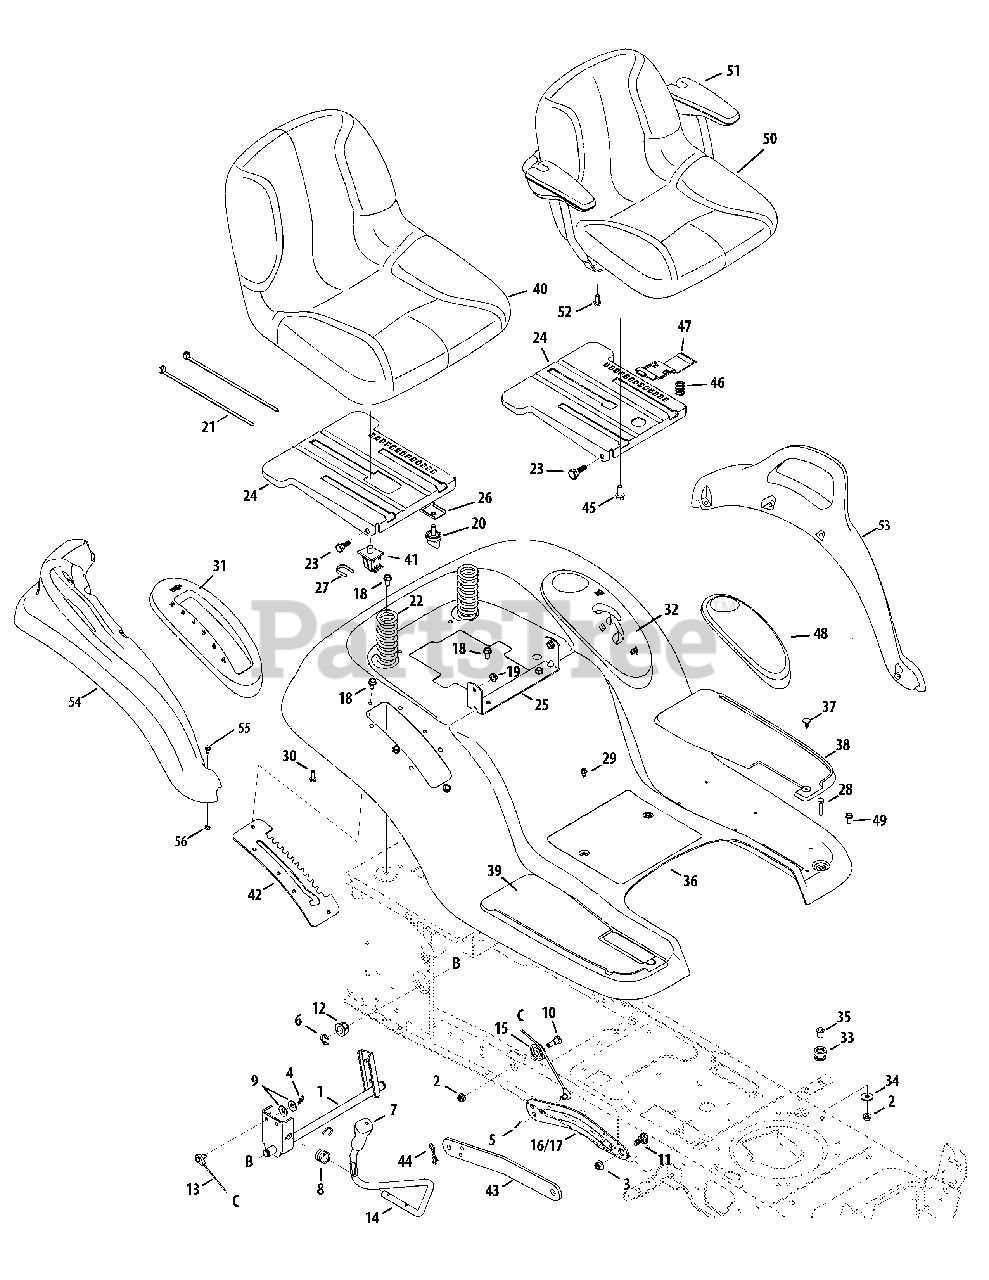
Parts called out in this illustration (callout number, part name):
1	Lift Shaft Ass’y
2	Flange Locknut 5/16-18 Gr. F, Ny lon
3	Flange Lock-Nut 3/8-16 Gr. F Ny lon
4	Int. Cotter Pin .072 x 1.13" Lg.
5	Bow-Tie Cotter Pin
6	E-ring .625 Shaft
7	Handle Grip
8	Torsion Spring
9	Cupped Washer .375 ID x .870 OD x .063
10	Shoulder Scr. .437 Dia x .47
11	Shoulder Screw .500 x .25 (46"/50")
11	Shoulder Bolt 3/8-16 x .625 (38"/42")
12	Hex Flange Bear ing .630 ID
13	Lift Cable, 16.16
14	Lift Handle
15	Roller Pulley
16	Lift Arm RH
17	Lift Arm LH
18	Hex Wash Hd. Tapp Scr. 5/16-18 x .75
19	Hex Flange L-Nut 5/16-18
21	Cable Tie
22	Compression Spring 1.50 x 3.9 x .20
23	Shoulder Screw
24	Seat Mount ing Bracket
25	Seat Pivot Bracket
26	Seat Bracket, Knob adjustment
27	Switch Retaining Clip
28	Hex Bolt 5/16-18 x 1.25
29	Hex Wash S-Tapp Scr 1/4-20 x .50
30	Hex Tapp Scr 1/4 x .75" Lg.
31	Lift Lever Cover
32	Shift Lever Cover
33	Grommet .4375 ID x .75
34	Flat Washer .344 ID x 1.0
35	Flange Spacer .3125 x .4375 x .625
37	Foot Pad Clips
38	Foot Pad LH
39	Foot Pad RH
40	Seat, High Back, Black
41	Seat Switch
42	Lift Bracket 6 positions (w/man pto)
42	Lift Bracket 6 positions (w/electric pto)
43	Lift Link (46"/50")
44	Bow-Tie Cotter Pin (46")
45	Hex. Hd. Flg. Scr. 3/8-16 x .875
46	Compression Spring .68 x 1.065 x .055
47	Seat Adjustment Lever
48	Cover (Hydrostatic Models only)
49	Hex Wash. Hd. Scr. 5/16-18 x .75 Gr. F Nyl.
50	Seat, High Back, Black (w/arm rest option)
51	Arm Rest (incl. R&L)
52	Pan TT Screw 5/16-18 x .75
53	Fender Cover LH
54	Fender Cover RH
55	Carriage Bolt 1/4-20 x 1.0
56	Sems Hex Nut 1/4-20
